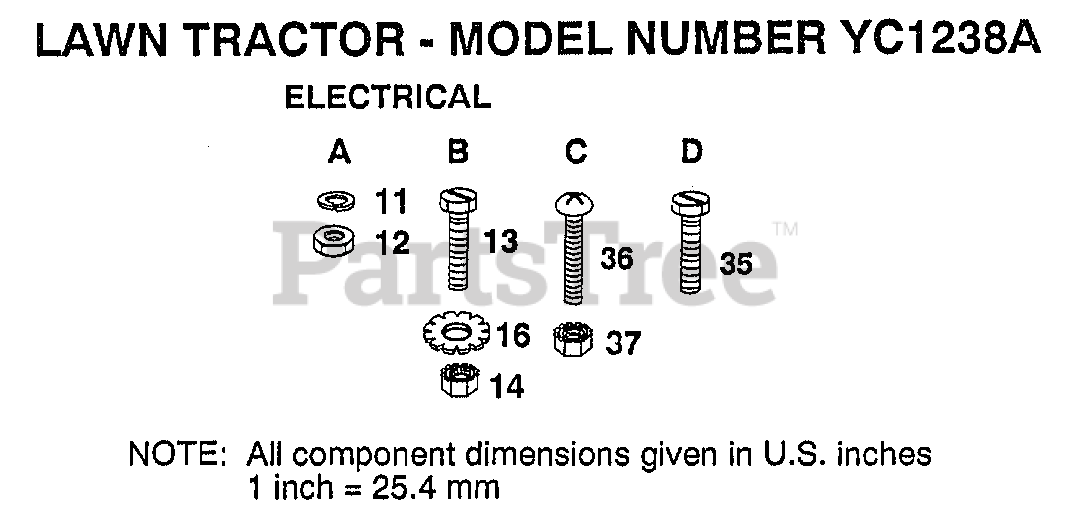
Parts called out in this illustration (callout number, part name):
12	NUT
13	BOLT
14	NUT
35	SCREW
37	"NUT,KEPS"
